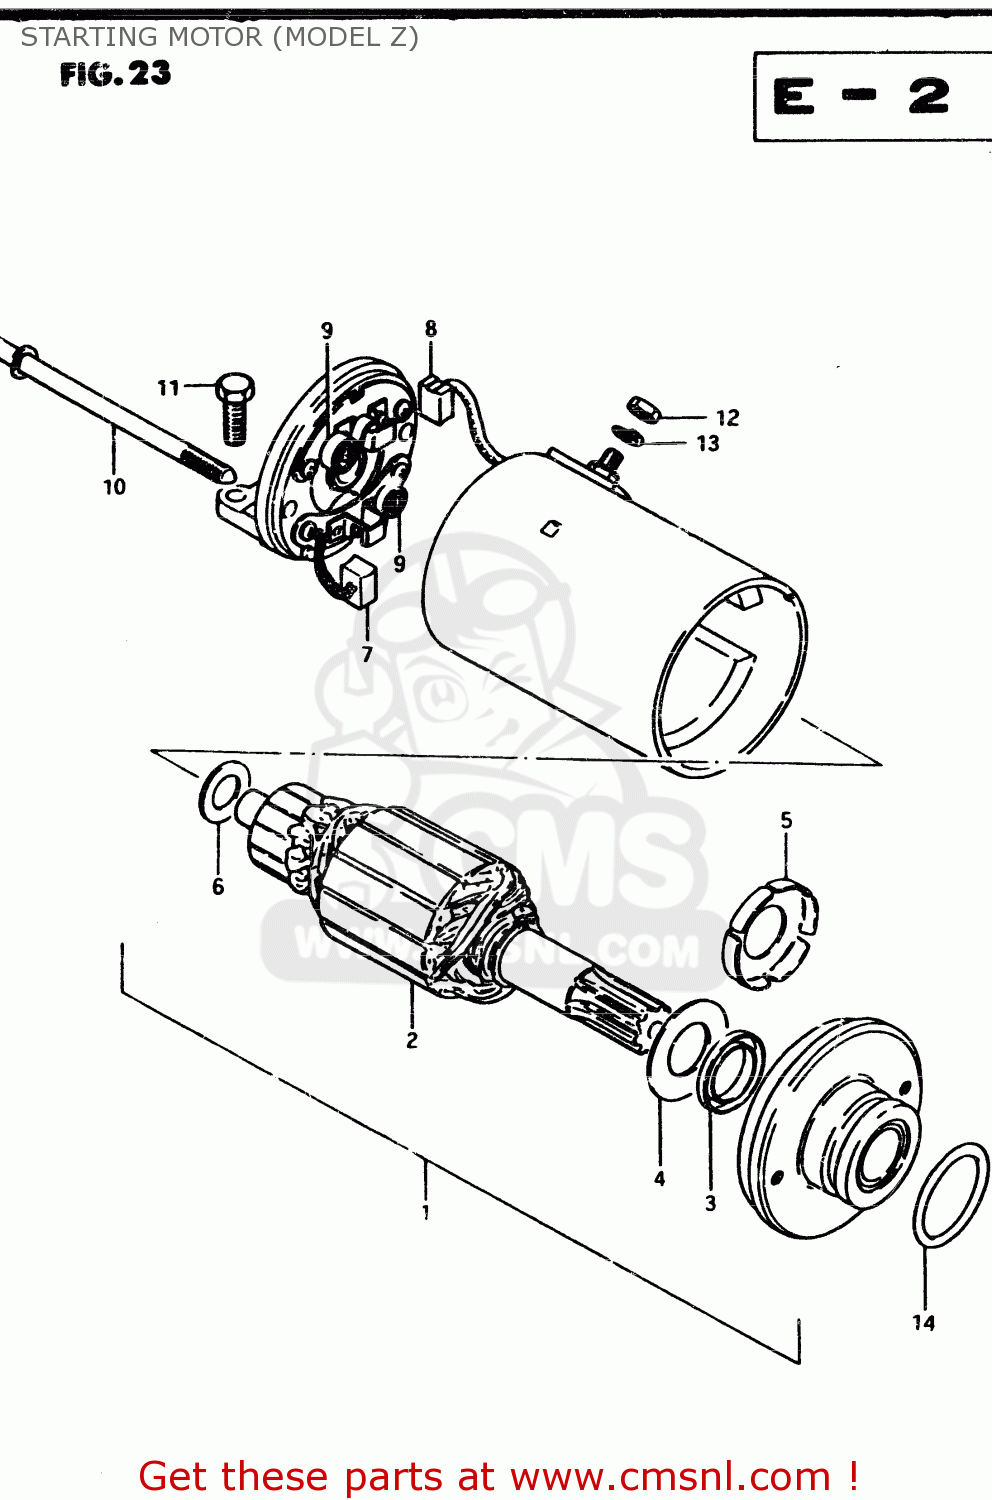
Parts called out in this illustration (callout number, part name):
1	MOTOR ASSEMBLY,STARTING
2	ARMATURE
3	SEAL,OIL
4	RING,SNAP
5	SHIM,ARMATURE
6	SHIM,ARMATURE
7	BRUSH(-)
8	BRUSH TERMINAL SET
9	SPRING
10	BOLT,STARTING MOTOR HOUSING
11	BOLT, UPPER
12	NUT 6MM
13	LOCK WASHER
14	O RING(D:2,ID:24.5)
